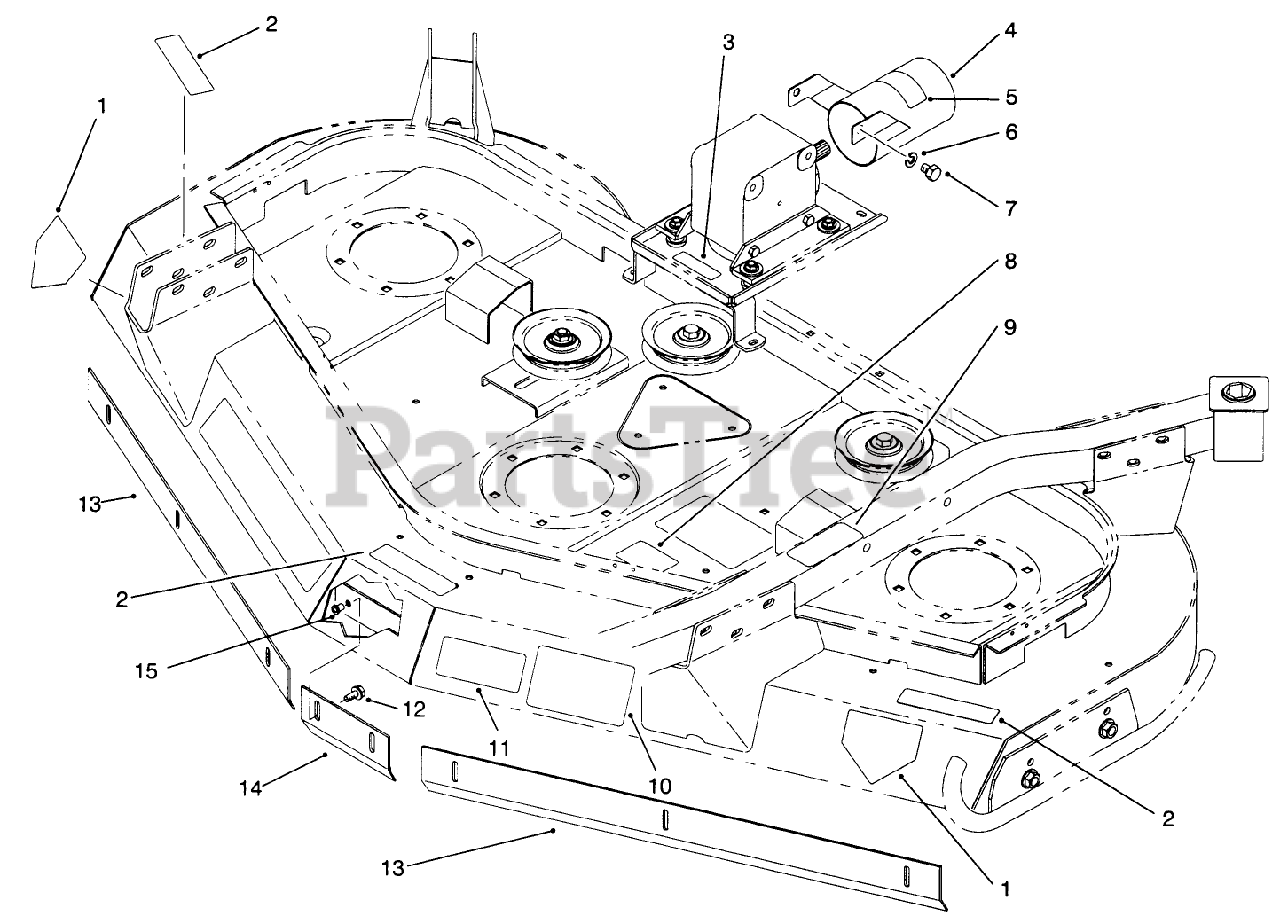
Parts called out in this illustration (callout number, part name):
1	DECAL-DANGER, INT'L
2	DECAL-DANGER
3	DECAL-LUBE
4	Guard-PTO Shaft
5	DECAL-DANGER
6	WASHER-LOCK
7	SCREW-HH
8	DECAL BLANK
9	DECAL-HOC
10	DECAL - WARNING
11	DECAL-TORQUE, BLADE BOLT
12	SCREW-HHF
13	Baffle-Side
14	Baffle-Center
15	NUT-INSERT
